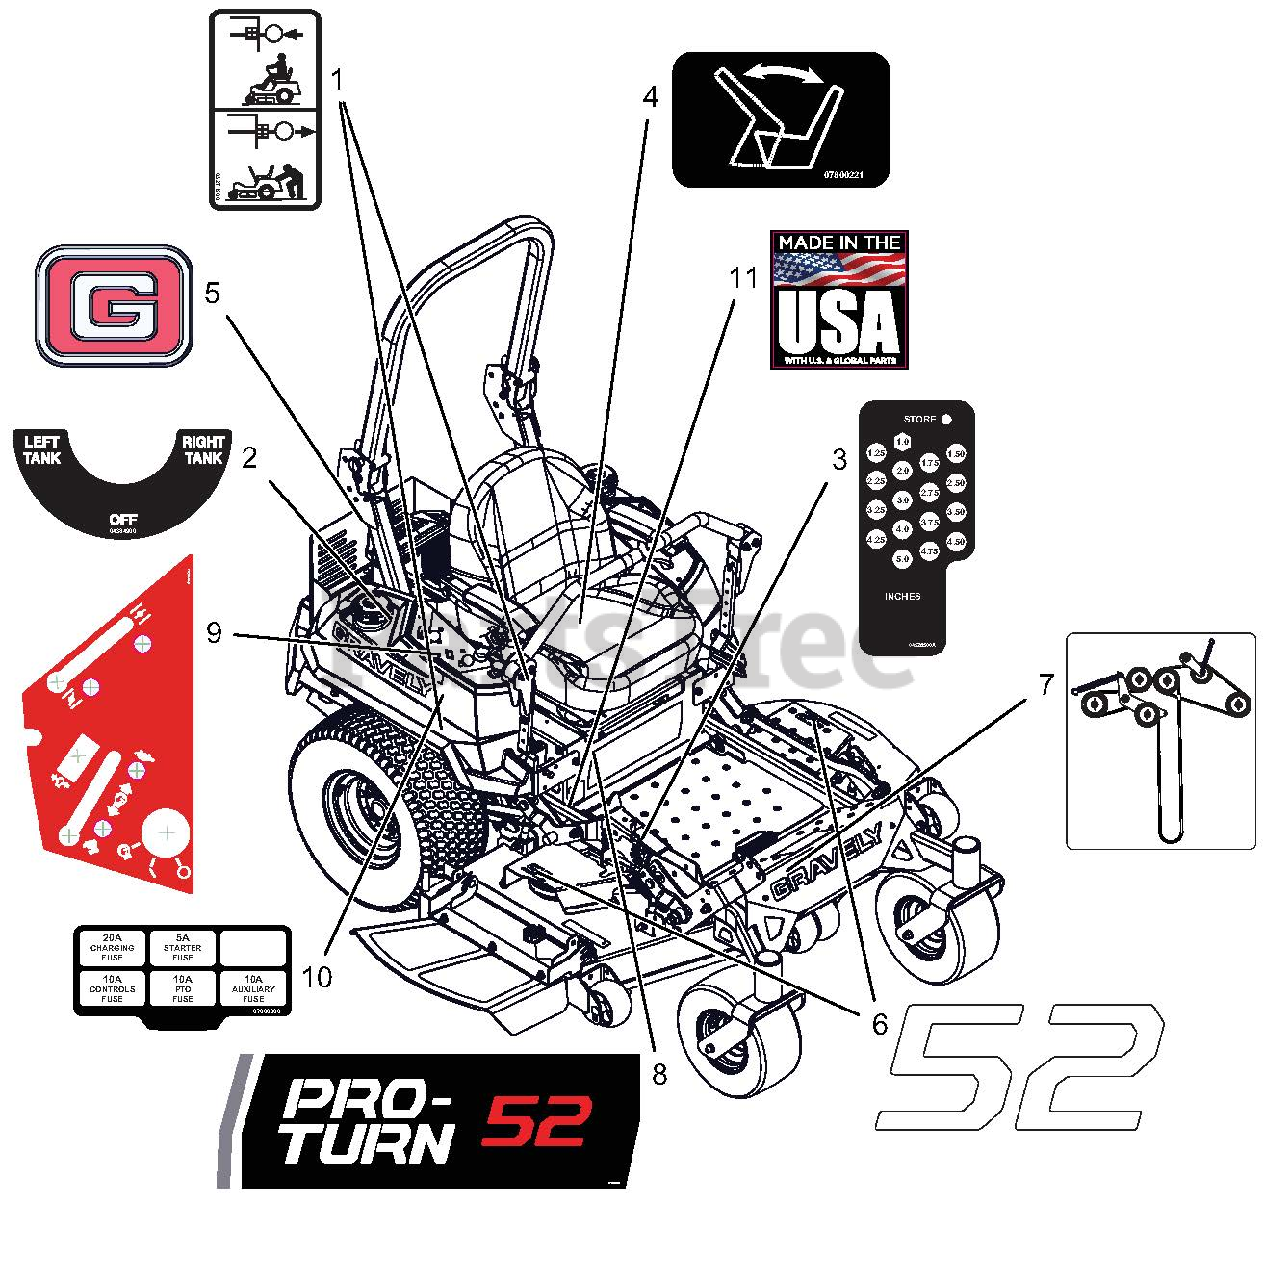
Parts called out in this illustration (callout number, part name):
1	DECAL, TRANSMISSION DISCONNECT
2	DECAL, FUEL VALVE
3	DECAL, HEIGHT OF CUT
4	DECAL - SEAT RELEASE
5	DECAL, GRAVELY BRAND
6	DECAL, 52"
7	DCL,BELT ROUTE-RH V-SIDE IDLER
8	DECAL, PRO-TURN 52
9	DECAL, NON-EFI CONTROL PANEL
10	DECAL, FUSE BLOCK
11	DECAL, MADE IN USA
